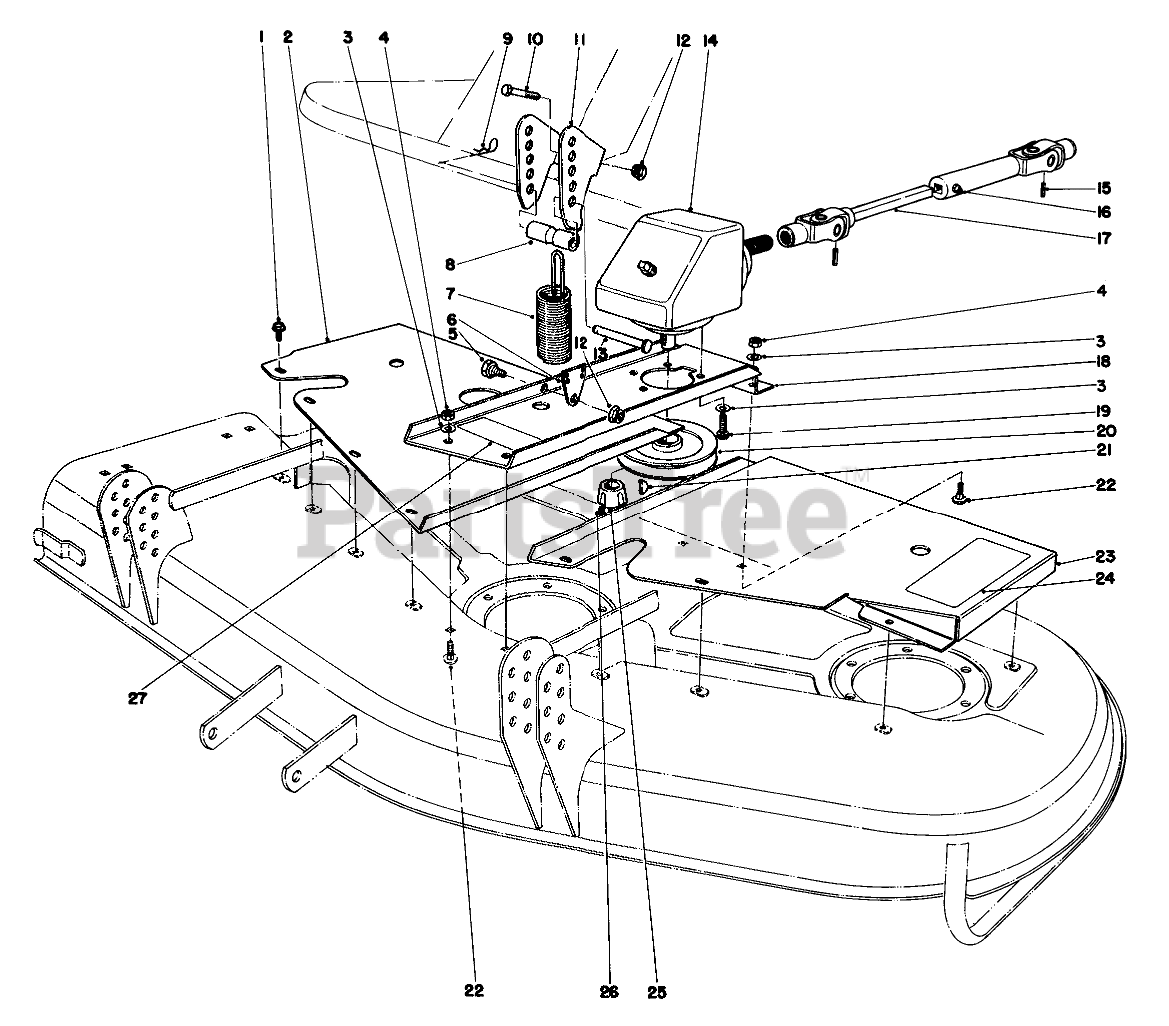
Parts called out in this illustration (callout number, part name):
1	SCREW-HHFTF
2	RH COVER WA R
3	WASHER-LOCK
4	NUT-HEX
5	BOLT-SHOULDER
6	SPRING END R
7	Spring-Extension
8	SPACER
9	PIN-HAIR
10	SCREW-HH
11	SPRING BRACKET R
12	NUT-HHF, WHIZ
13	PIN-CLEVIS
14	GEAR BOX ASM
15	PIN-ROLL
16	FITTING-GREASE
17	UNIVERSAL JOINT
18	Base-Bear Box
19	SCREW-HSH
20	PULLEY WA BO
21	KEY-WOODRUFF
22	SCREW-CARR
23	LH COVER WA R
24	DECAL
25	BUSHING-LOCK, TAPER
26	SCREW-SET, HSH
27	Decal-Caution
